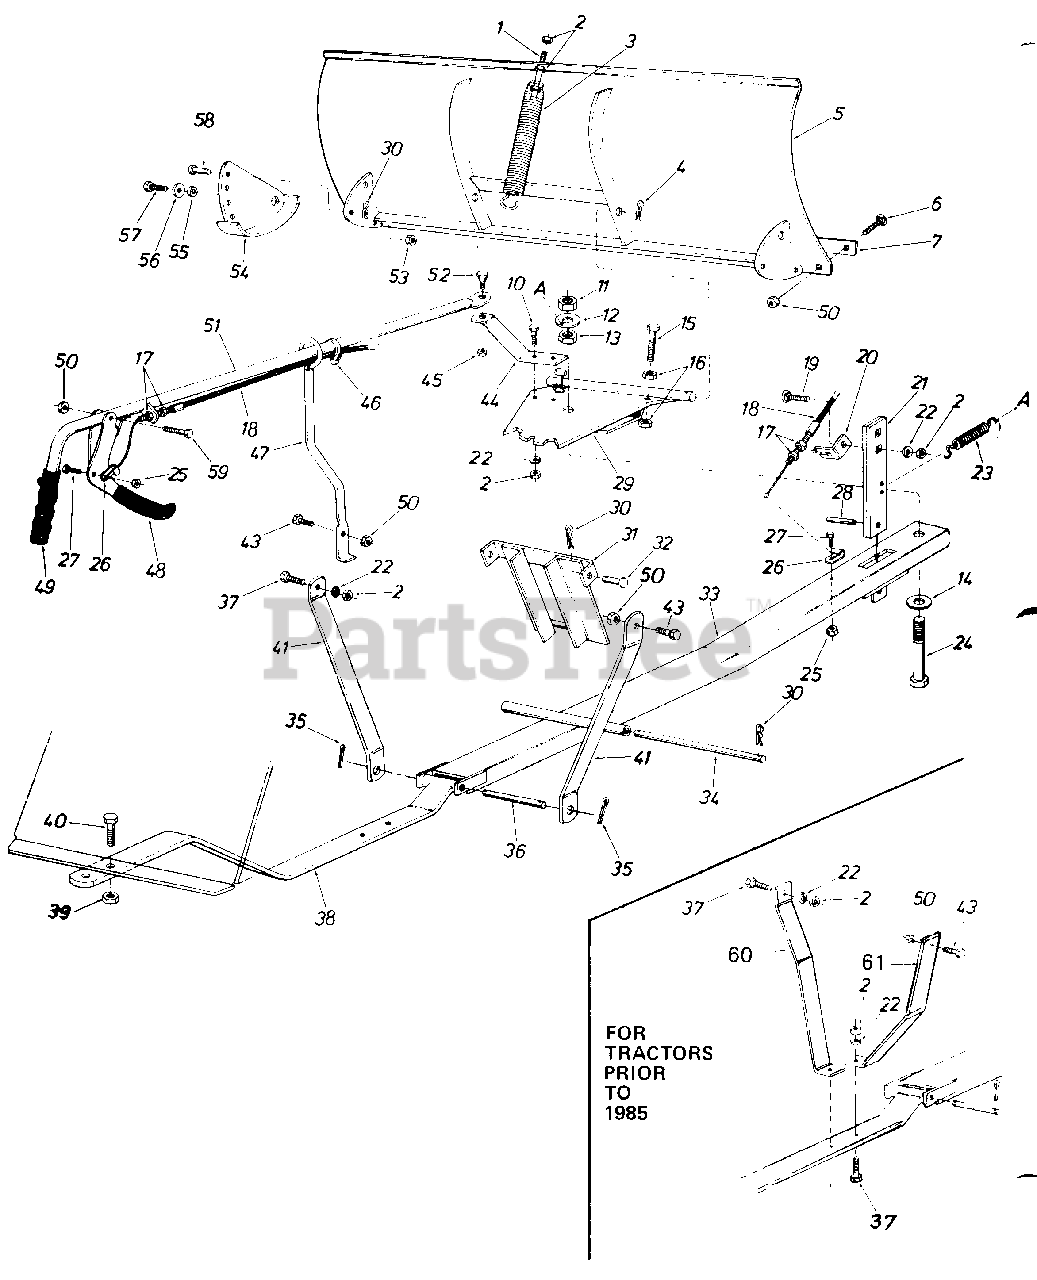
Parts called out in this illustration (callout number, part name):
1	Hex Scr. 3/8-16 x 4.50" Lg. *
2	Hex Nut 3/8-16 Thd.*
3	Blade Adjustment Spring
4	Hair Pin Coter 5/32" Dia.
5	48" Blade Ass'y.
6	Carriage Bolt 5/16-18 x .75" Lg.
7	Wear Plate 48"
10	Hex Scr. 3/8-16 x 1.00" Lg. *
11	Hex L.Nut 3/4-10 Thd.
12	Fl.Wash..810" I.D. x 2.00" O.D.
13	Hex Jam Nut 3/4-10 Thd. *
14	Fl.Wash..810" I.D. x 2.00" O.D.
15	Hex Scr. 1/2-13 x 2.00" Lg.*
16	Hex Nut 1/2-13 Thd. *
17	Hex Jam Nut 5/16-24 Thd.*
18	Control Cable Ass'y.
19	Carriage Bolt 3/8-16 x 1.25" Lg.*
20	Cable Guide Bracket
21	Angle- Lock Bar
22	L.Wash. 3/8" Scr.*
23	Angle Lock Spring
24	Hex Scr. 3/4-10 x 4.00" Lg.
25	Hex L.Nut 1/4-20 Thd.
26	Clevis Lanyard Fiting
27	Hex Scr. 1/4-20 x .75" Lg.*
28	Spring Pin Spirol 1/4" Dia. x 1.00" Lg.
29	Pivot Plate Ass'y.
30	HairPin Coter3/32" Dia.
31	Guide Bracket Ass'y.
32	Clevis Pin 1/2" Dia. x 1.00" Lg.
33	Push Bar Assy.
34	Lift Shaft
35	Coter Pin 5/32" Dia. x 1.00" Lg.*
36	Pivot Pin
37	Hex Scr. 3/8-16 x 1.25" Lg.*
38	Hanger Bracket Ass'y.
39	Hex L.Nut 5/8-11 Thd.
40	Hex Scr. 5/8-11 x 1.50" Lg.*
41	Hanger Link
43	Hex 5/16-18 x 1.00" Lg. *
44	Blade Pivot Bracket
45	Hex Jam Nut 3/8-16 Thd.
46	Nylon Cable Tie
47	Tube Guide Ass'y.
48	Clutch Grip Ass'y.
49	Grip-3/4" Handle
50	Hex L-Nut 5/16-18 Thd.
51	Tube Handle Ass'y.
52	Shld. Scr.-Special 3/8-16 Thd.
53	Hex L.Nut 3/8-16 Thd.
54	Skid Assembly
55	Spacer
56	Fl.Wash..385" I.D. x 1.00" O.D.
57	Hex Scr. 3/8-16 x .75" Lg.*
58	ClevisPin5/16" Dia. x .75" Lg.
59	Hex Scr. 5/16-18 x 1.50" Lg.
60	Mounting Brkt.L.H.
61	Mounting Brkt.R.H.
